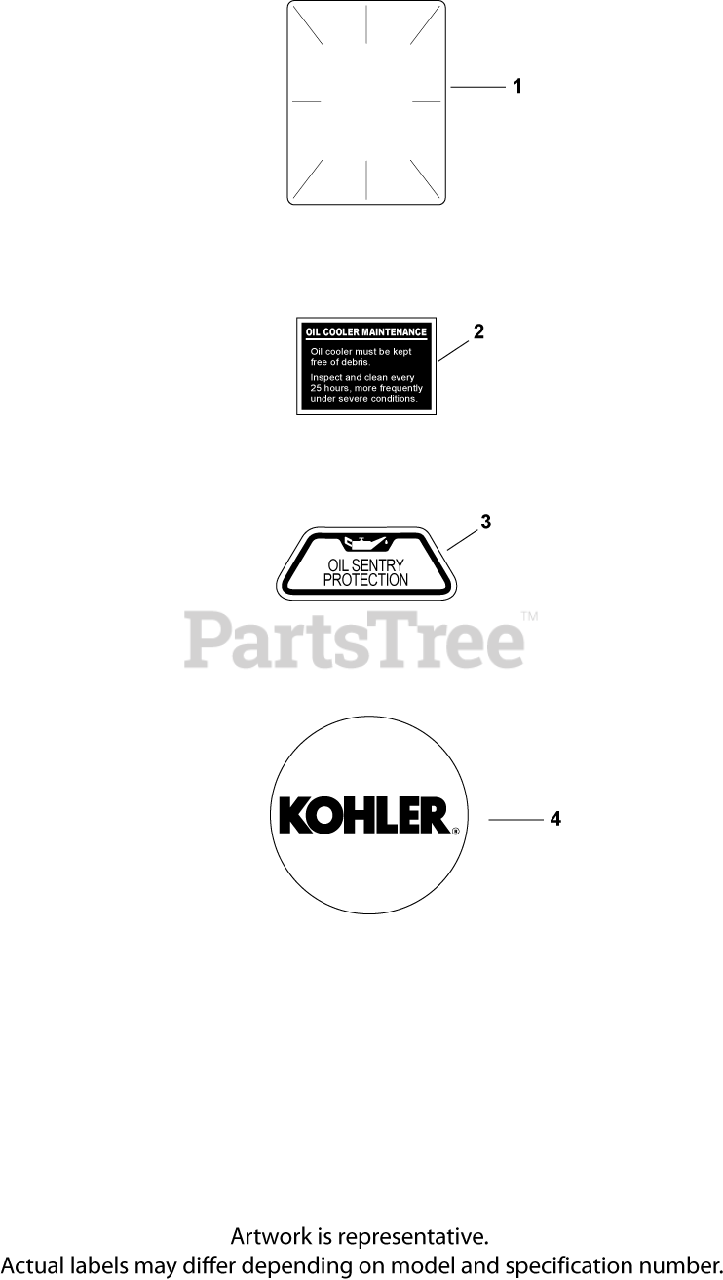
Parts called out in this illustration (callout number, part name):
1	DECAL, CLEAR LAMINATE USE 25 113 70-S
2	DECAL, OIL COOLER - (#DSC)
3	DECAL, OIL SENTRY - (#DSC)
4	DECAL, GRASS SCREEN USE 24 113 499-S
